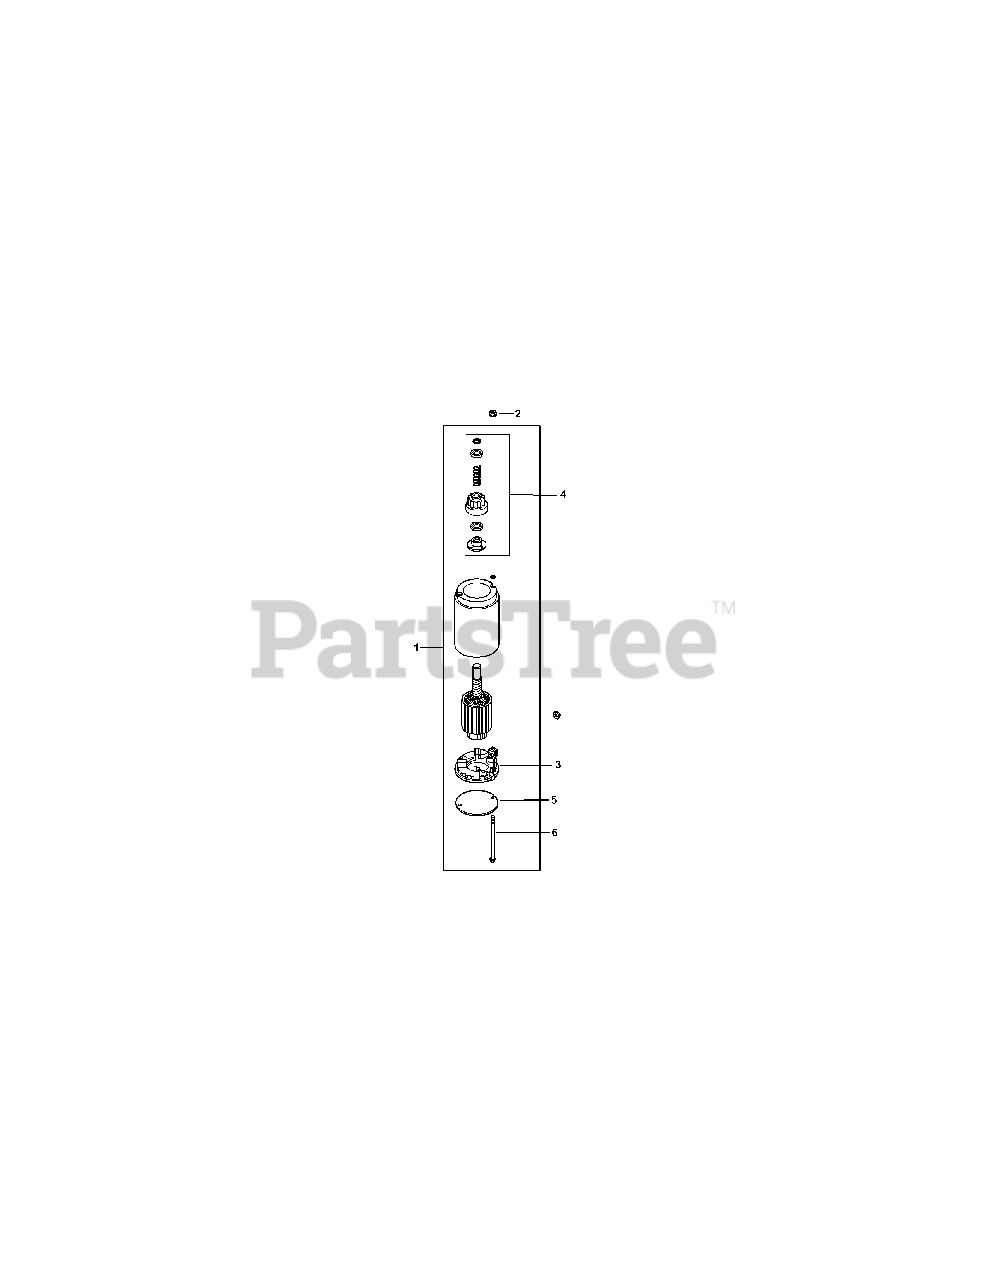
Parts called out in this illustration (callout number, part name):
1	Starter Assembly
2	Free Spinning Flange Nut, #10-24
4	Drive Kit (J.E.)
5	Drive End Cap (J.E.)
